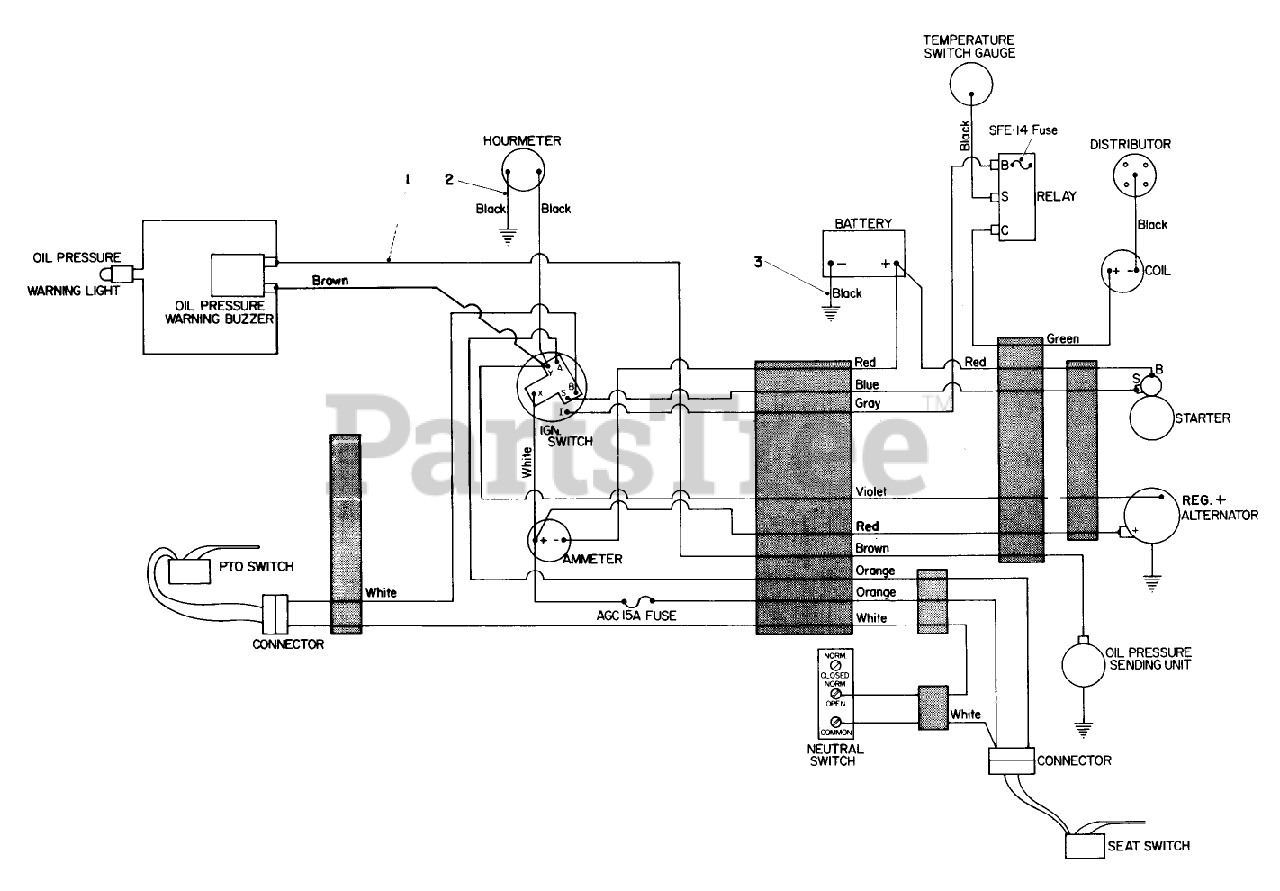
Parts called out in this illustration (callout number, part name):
1	WIRE HARNESS
2	Wire Harness
3	Cable Ground
